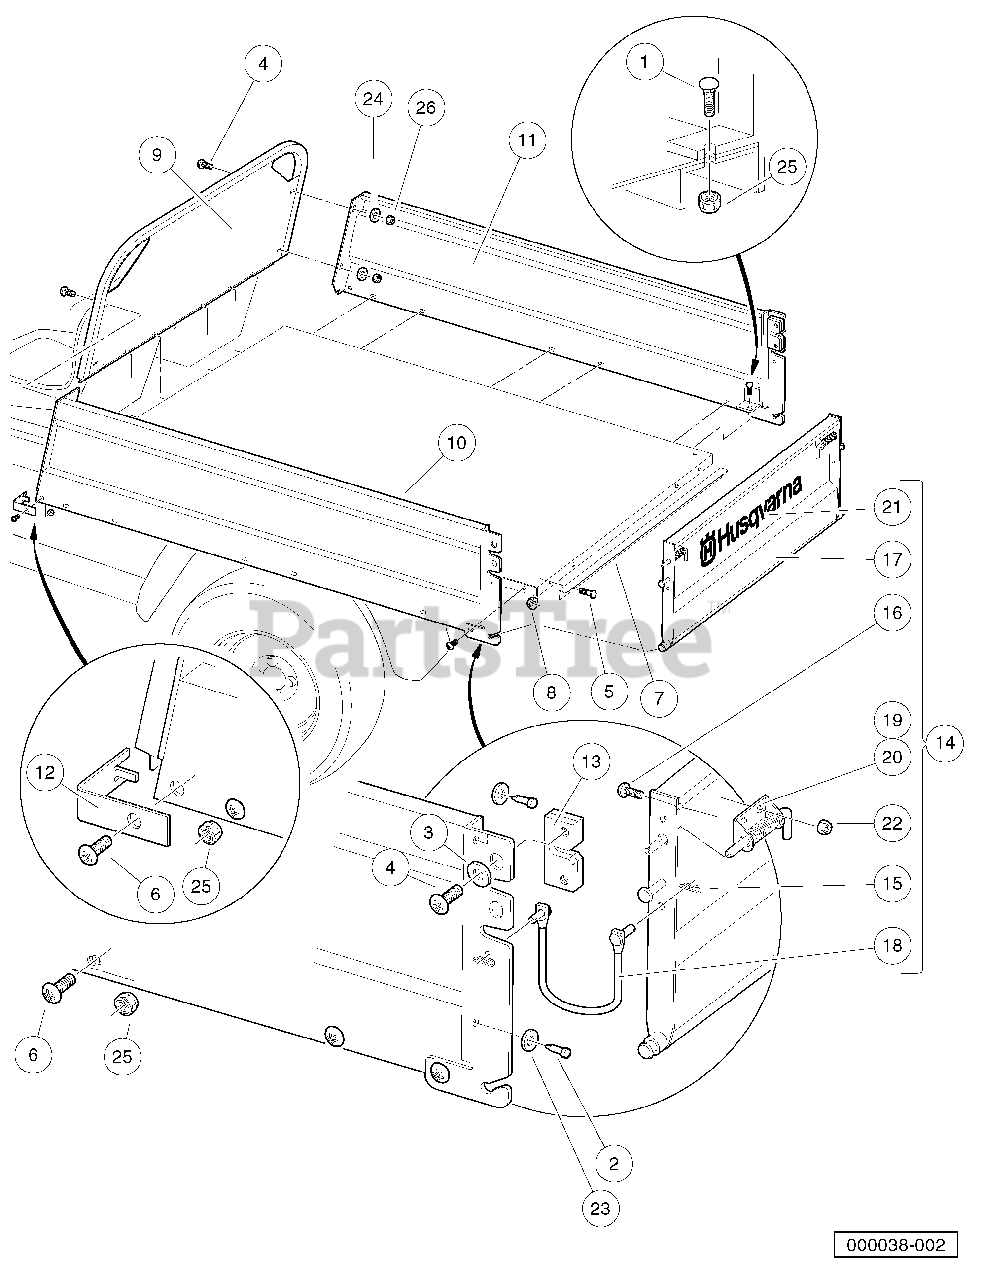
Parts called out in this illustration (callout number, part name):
1	Bolt, Carriage, 5/16-18 X 1.00
2	Bumper, Rubber
3	Washer, 1/4" Type B Flat
4	Screw, 1/4-20 X 0.75 Torx Truss-Head
5	Stud, Self-Clinching Flush Head
6	Screw, 5/16-18 X 0.88 Torx Truss-Head
7	Box Bed Tailgate Angle
8	Locknut, 5/16-18 Hex Flange
9	Front Panel Weldment
10	Left Panel Weldment
11	Right Panel Weldment
12	Front Corner Cap
13	Slam Latch
14	Assembly, Tailgate
15	Hair Pin Clip
16	Screw, 1/4-20 X 0.75 Torx Truss-Head
17	Tailgate, Weldment
18	Tether Assembly
19	Spring Latch Left
20	Spring Latch Right
21	Decal, Husqvarna, Tailgate
22	Locknut, 1/4-20 Nylon Insert
23	Washer, Rubber, 3/8
24	Washer, 1/4 Type A Narrow Flat
25	Locknut, 5/16-18 Nylon Insert
26	Locknut, 1/4-20 Nylon Insert
